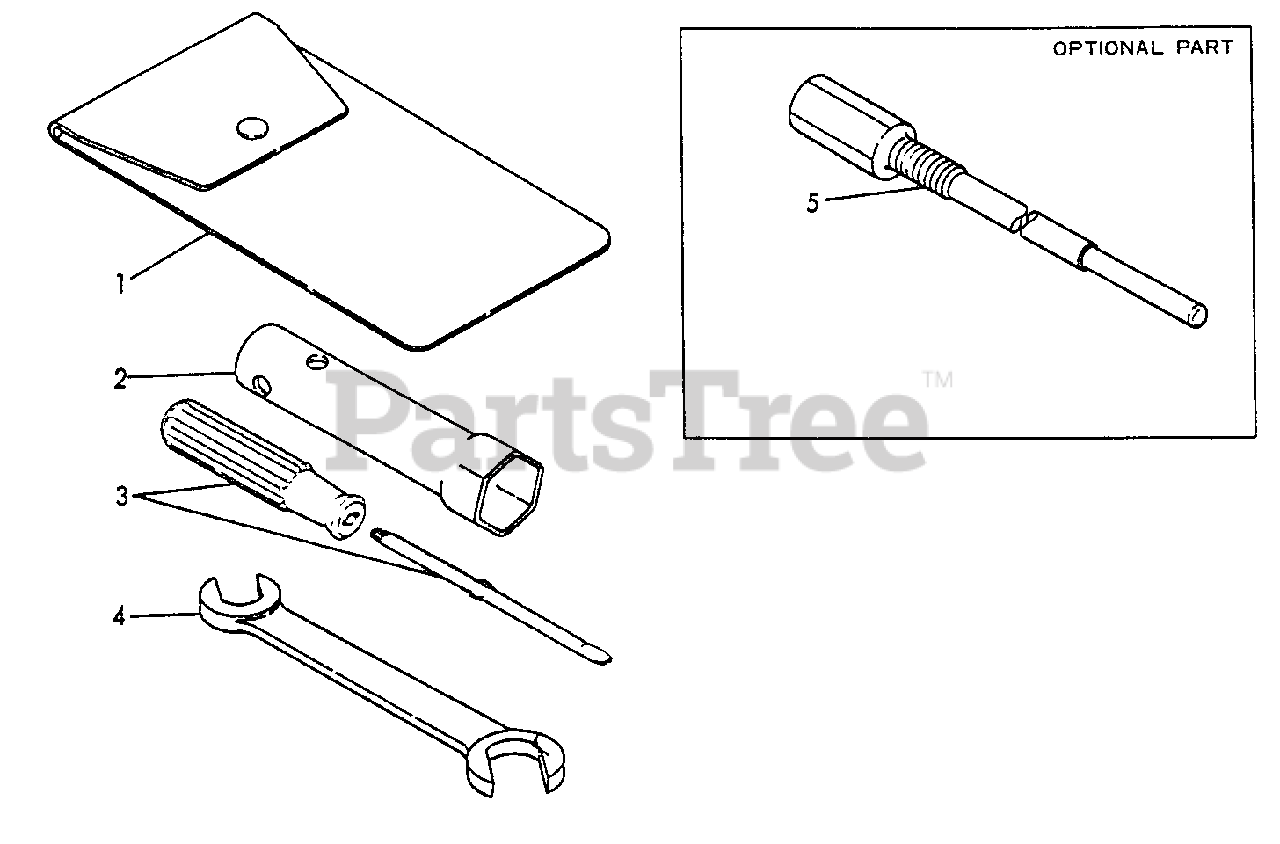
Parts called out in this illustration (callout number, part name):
1	BAG, TOOL
2	SOCKET WRENCH - 21mm
3	SCREWDRIVER
4	SPANNER - 10X12mm
5	REMOVER, ROTOR
